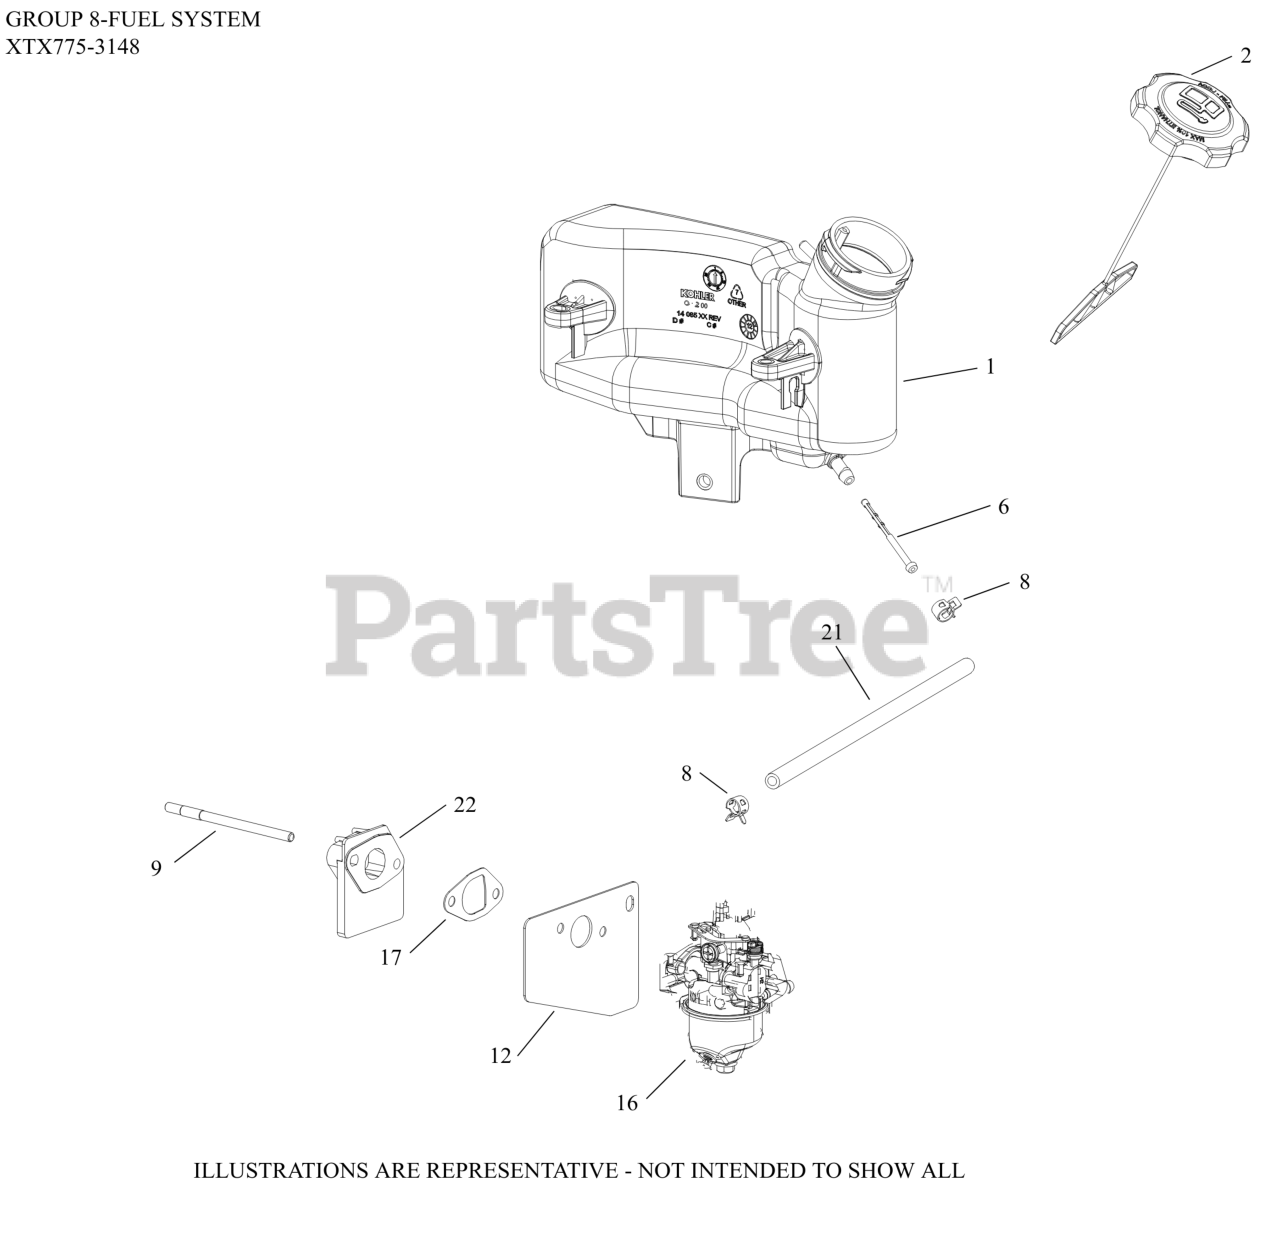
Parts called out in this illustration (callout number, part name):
1	TANK, FUEL
2	FUEL CAP ASSEMBLY
6	FILTER, FUEL IN-NIPPLE
8	CLAMP, HOSE (NON-CALIF)(#1423710S)
9	STUD,M6X1.0X100.2MM
12	KIT, CARBURETOR HEAT SHIELD GASKET
16	KIT, CARBURETOR 13 MM STD CHOKE
17	KIT, INTAKE GASKET
21	HOSE, FUEL LOW-PERMEATION
22	KIT, SPACER
NI	KIT, HIGH ALTITUDE - USE 14 755 04-S
NI	KIT, CARBURETOR REPAIR (RUIXING)
